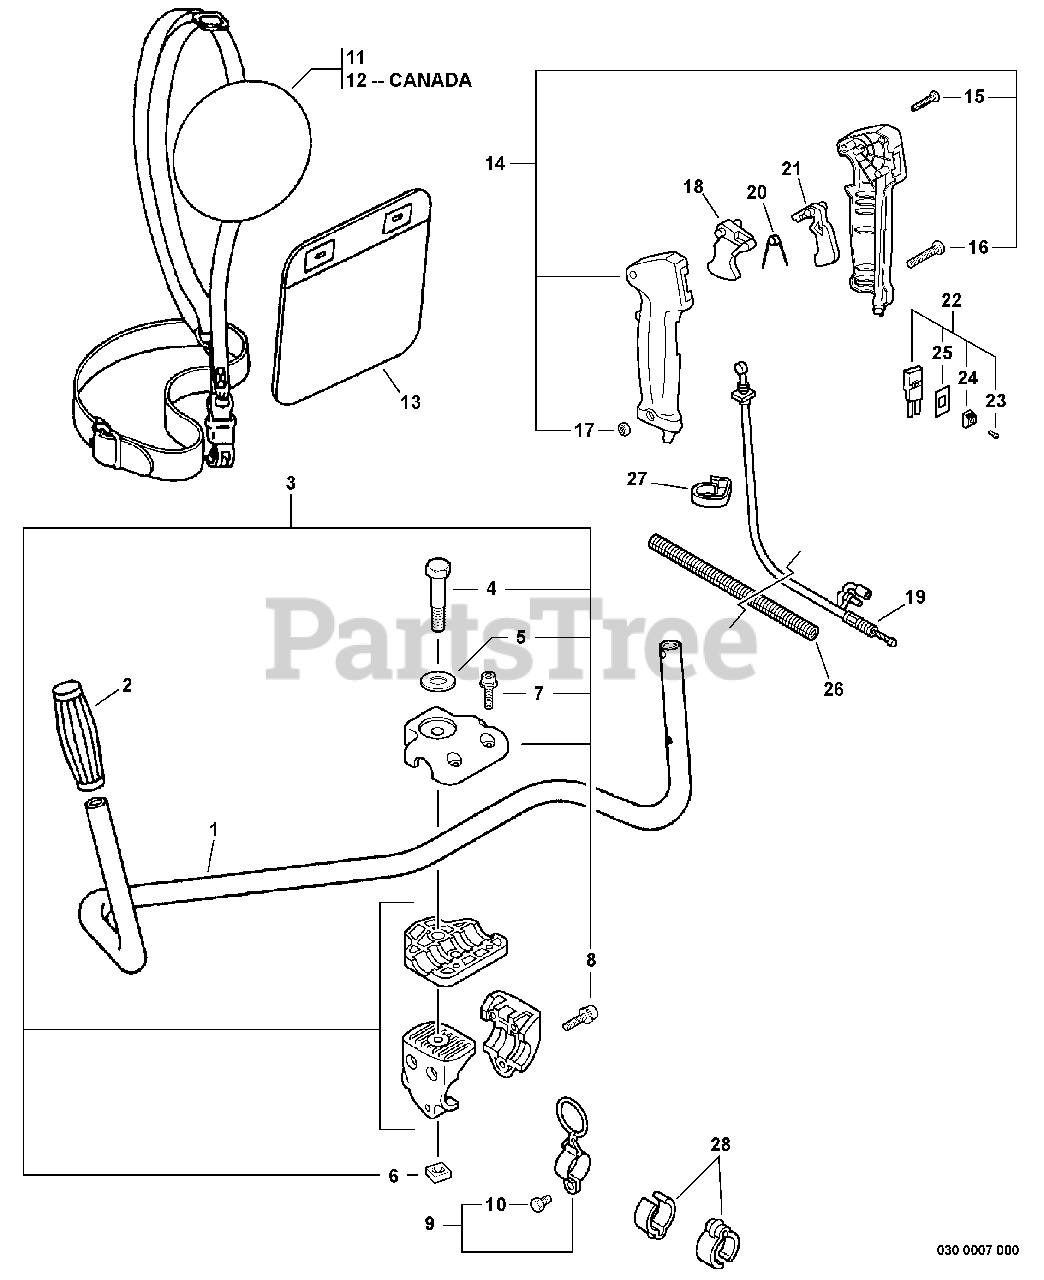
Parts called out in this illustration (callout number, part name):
1	HANDLEBAR
2	GRIP, HANDLE
3	BRACKET KIT, HANDLEBAR
4	BOLT 8×55
5	WASHER 8
6	NUT 8×1.25
7	BOLT 5×20
8	BOLT 5×30
9	HANGER SET, HARNESS
10	BOLT 5×12
11	HARNESS, SHOULDER
12	HARNESS, SHOULDER
13	PAD, HIP
14	CONTROL HANDLE KIT
15	SCREW 3×25
16	SCREW 5×30
17	NUT M5
18	TRIGGER, THROTTLE
19	CABLE, THROTTLE
20	SPRING, TORSION
21	LOCKOUT, THROTTLE
22	SWITCH, ON-OFF
23	SCREW 3×10
24	KNOB, SWITCH - ORANGE
25	LABEL, SWITCH
26	TUBE, FLEXIBLE 7×790
28	CLIP, CABLE 25 MM
